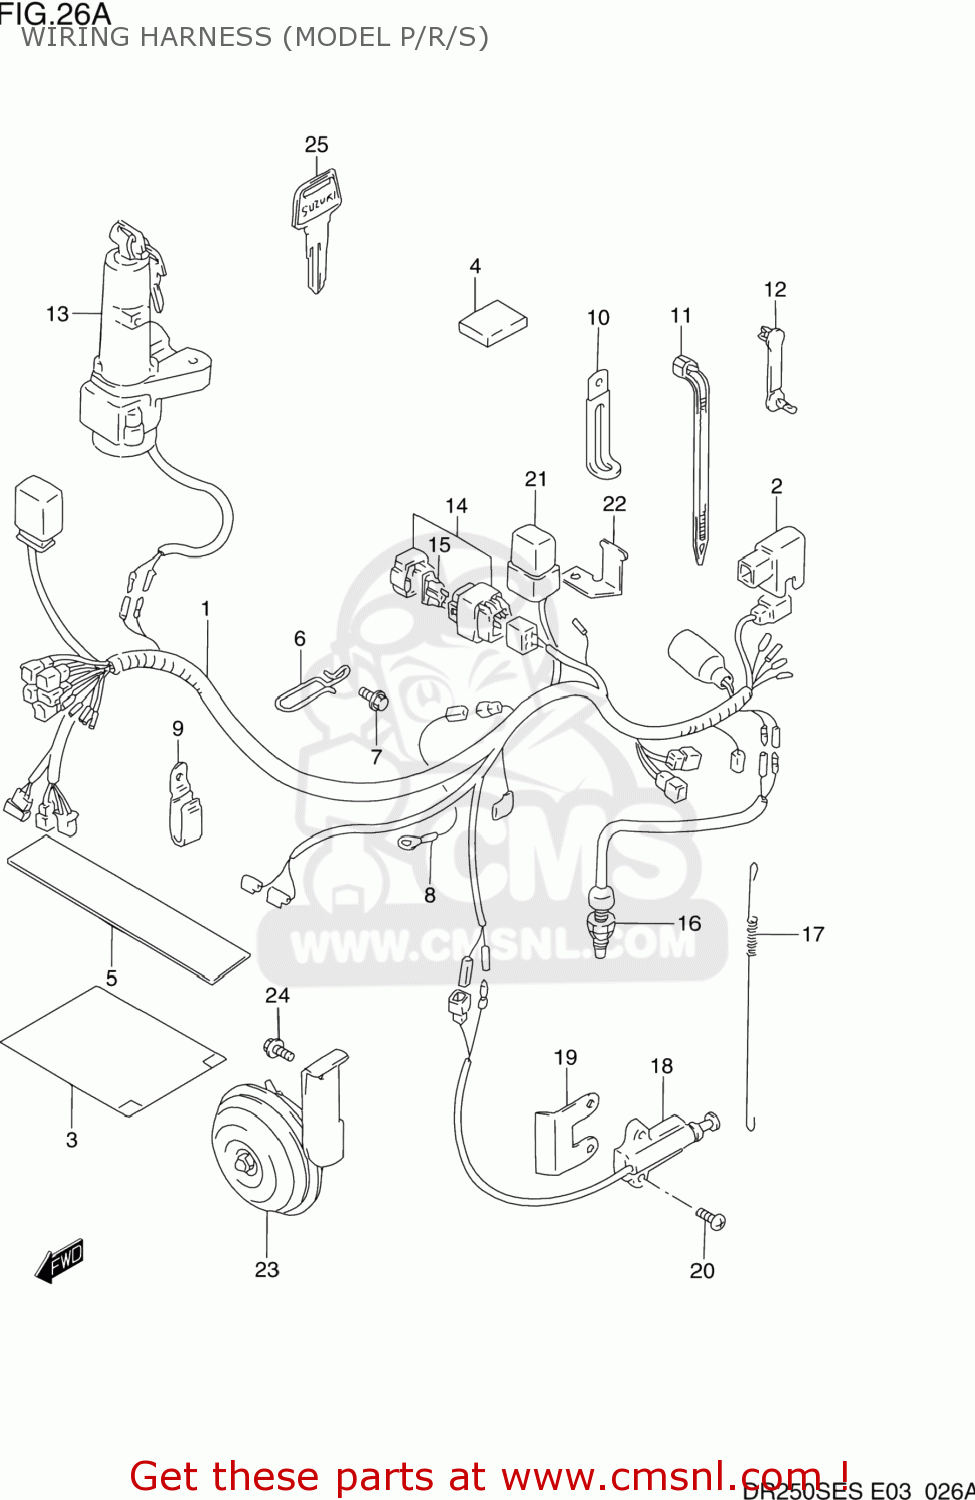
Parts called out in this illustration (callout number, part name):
1	HARNESS,WIRING
2	CAP,BATTERY PLUS
3	COVER,WIRING HARNESS
4	CUSHION
5	PROTECTOR,WIRING HARNESS
6	GUIDE,WIRING HARNESS
7	BOLT
8	WIRE
9	CLAMP
10	CLAMP
11	CLAMP
12	CLAMP(L:33)
13	SWITCH ASSEMBLY,IGNITION
14	BOX ASSY,FUSE
15	FUSE(20A)
16	SWITCH ASSY,STOP LAMP
17	SPRING
18	SWITCH ASSEMBLY,SIDE STAND
19	PROTECTOR,SIDE STAND SWITCH
20	SCREW
21	RELAY ASSY
22	BRACKET,FUSE
23	HORN ASSEMBLY
24	BOLT
25	KEY,BLANK
